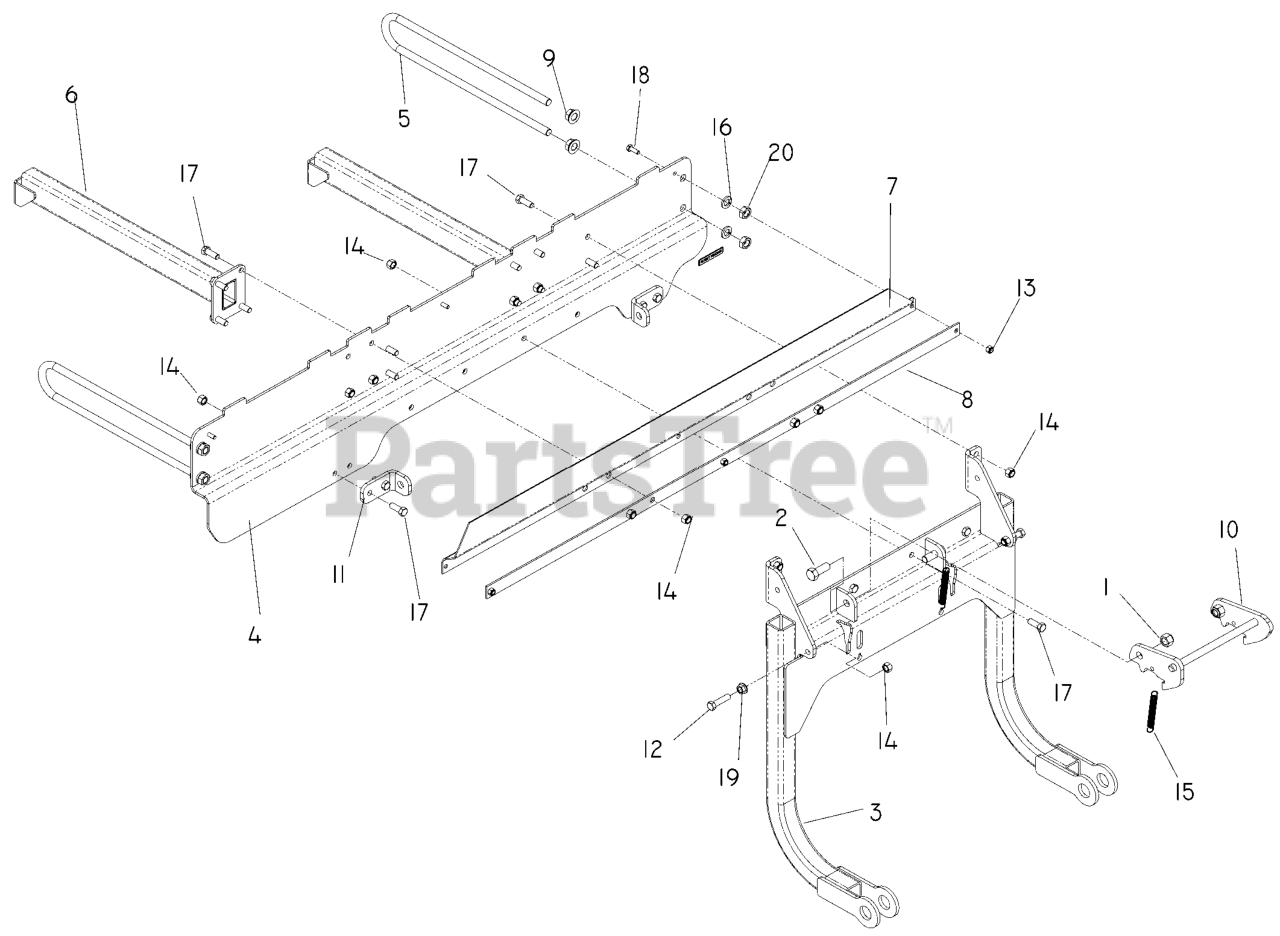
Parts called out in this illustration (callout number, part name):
1	NUT 1/2-13 HEX NYLOC ZD
2	HCS 1/2-13 X 1-1/4
3	HITCH WELDMENT
4	MOUNT Z BRACE
5	SUPPORT, OUTER
6	SUPPORT ARM WELDMENT
7	SEAL, RUBBER
8	SEAL STRAP
9	NUT 1/2-13 HEX
10	LATCH WELDMENT
11	BRACKET, SUPPORT
12	HCS 3/8C X 1 1/2
13	NUT.1/4-20.HEX.NYLOC.ZD
14	NUT 3/8-16 NYLOC
16	WASHER 1/2" SPLIT LOCK
17	HCS 3/8-16X1.GRD.5.ZD
18	HCS 1/4C X 3/4 HCS
19	NUT 3/8C WHIZ
20	NUT 1/2 HEX JAM
